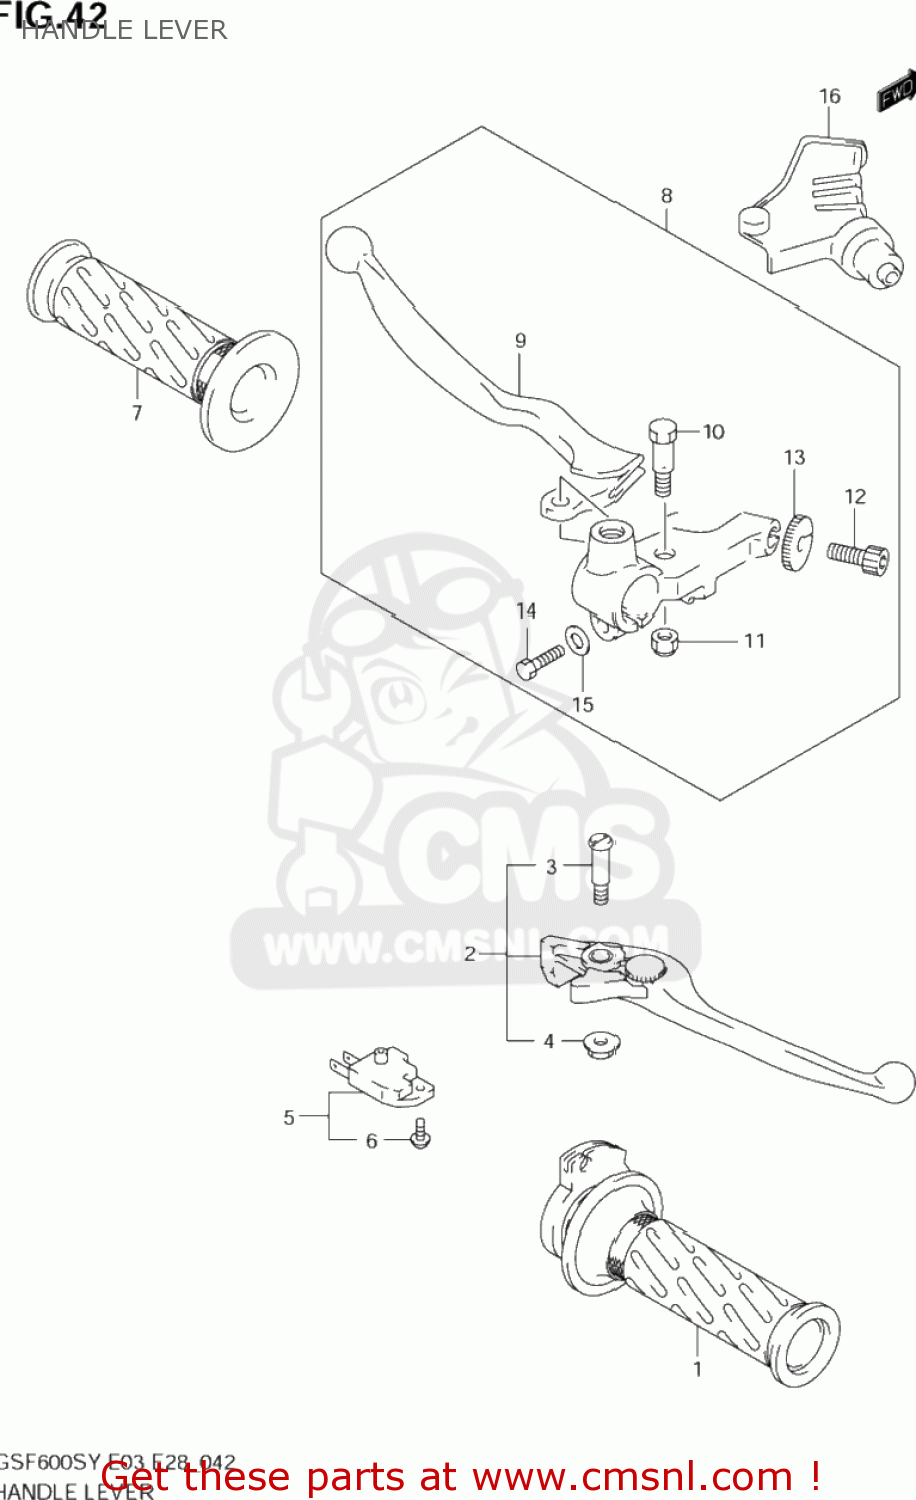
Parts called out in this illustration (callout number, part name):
1	GRIP,THROTTLE
2	LEVER ASSY,BRAKE
3	BOLT,LEVER PIVOT
4	NUT
5	SWITCH ASSEMBLY,STOP
6	SCREW
7	GRIP,LEFT
8	LEVER ASSY,CLUTCH
9	LEVER,CLUTCH
10	BOLT,LEVER SET
11	NUT
12	ADJUSTER,CABLE
13	NUT,CABLE ADJUSTER
14	BOLT
15	WASHER
16	COVER,CLUTCH LEVER
